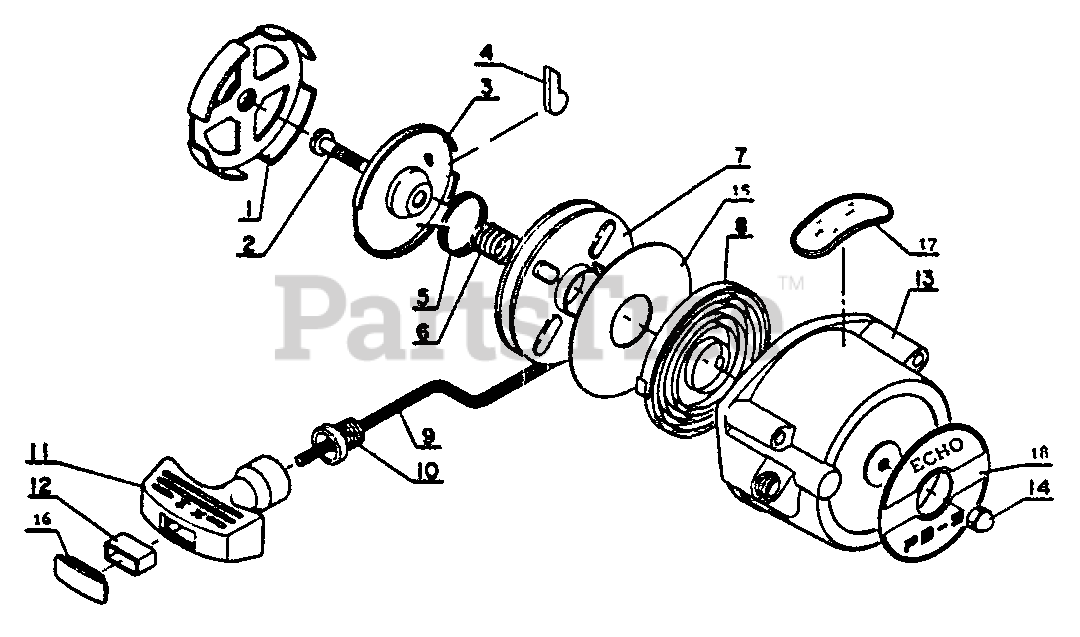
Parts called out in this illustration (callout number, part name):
1	CATCHER, PAWL
3	PLATE, FRICTION
4	PAWL, STARTER
5	SPRING, RETURN
6	SPRING
7	REEL, ROPE
8	SPRING, REWIND
9	ROPE, STARTER - 4X880
10	GUIDE, ROPE
11	GRIP, STARTER
12	RING, RETAINING
13	CASE, STARTER
14	NUT - 5 -- CAP
15	PLATE, STARTER
17	LABEL - CAUTION
18	LABEL - MODEL
